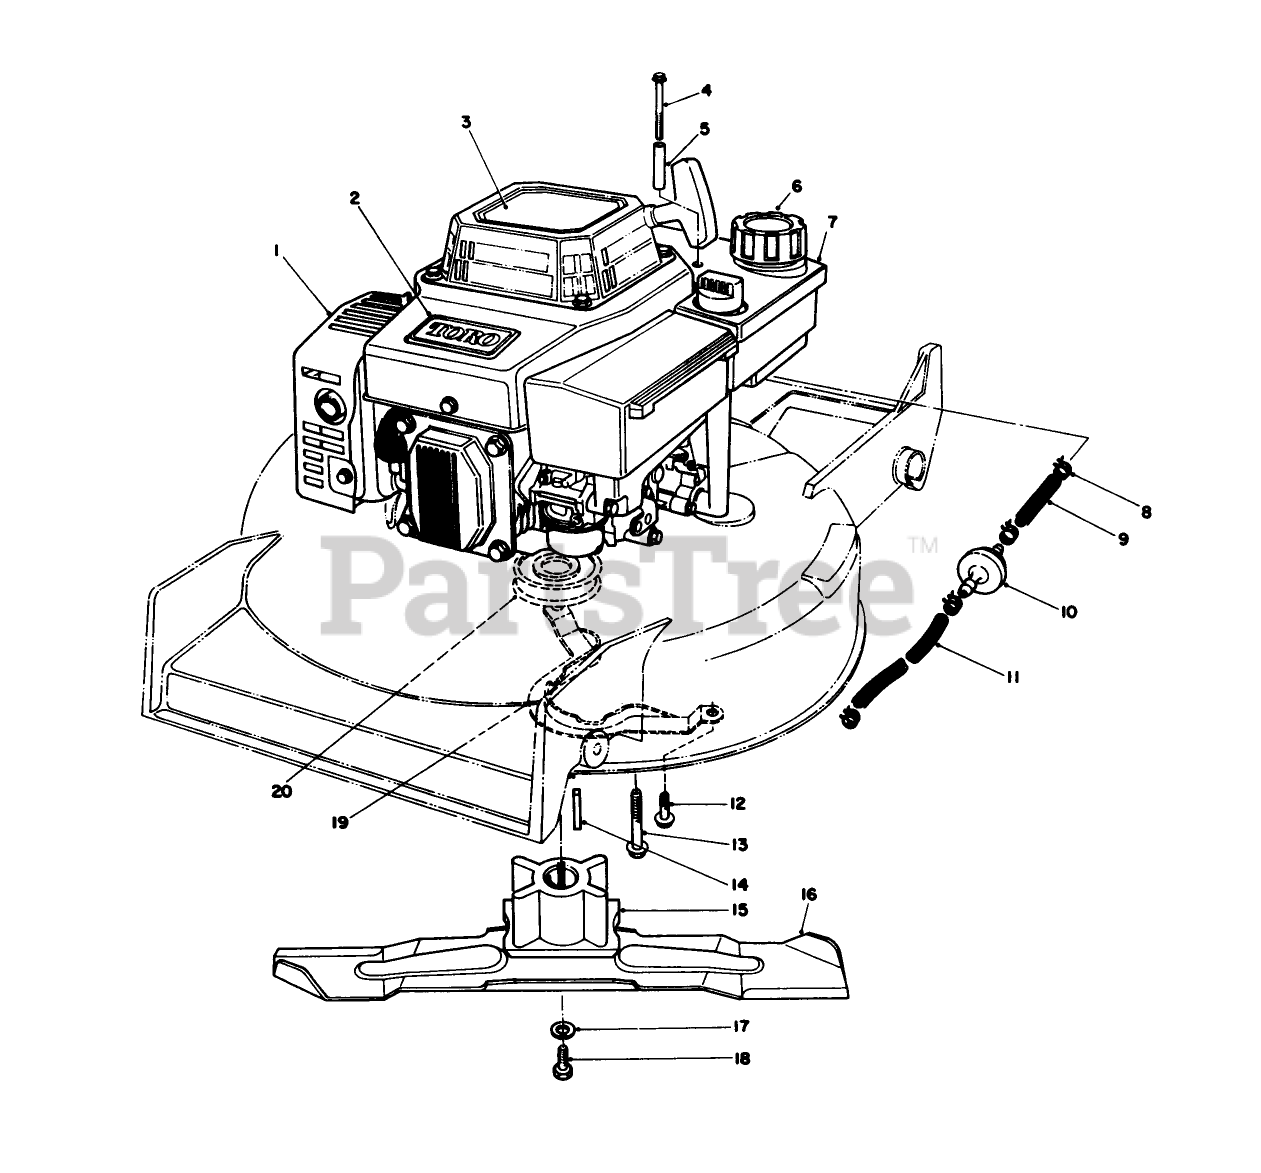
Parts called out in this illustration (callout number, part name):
1	Engine
4	THRD FORMING SCREW
5	TUBULAR SPACER
6	GAS CAP ASM
7	TANK ASM
8	CLAMP-FUEL LINE
9	HOSE-FUEL
10	FILTER-FUEL
11	HOSE-FUEL
14	KEY-SQUARE
17	WASHER-LOCK
18	SCREW-BLADE
20	PULLEY-DRIVER
